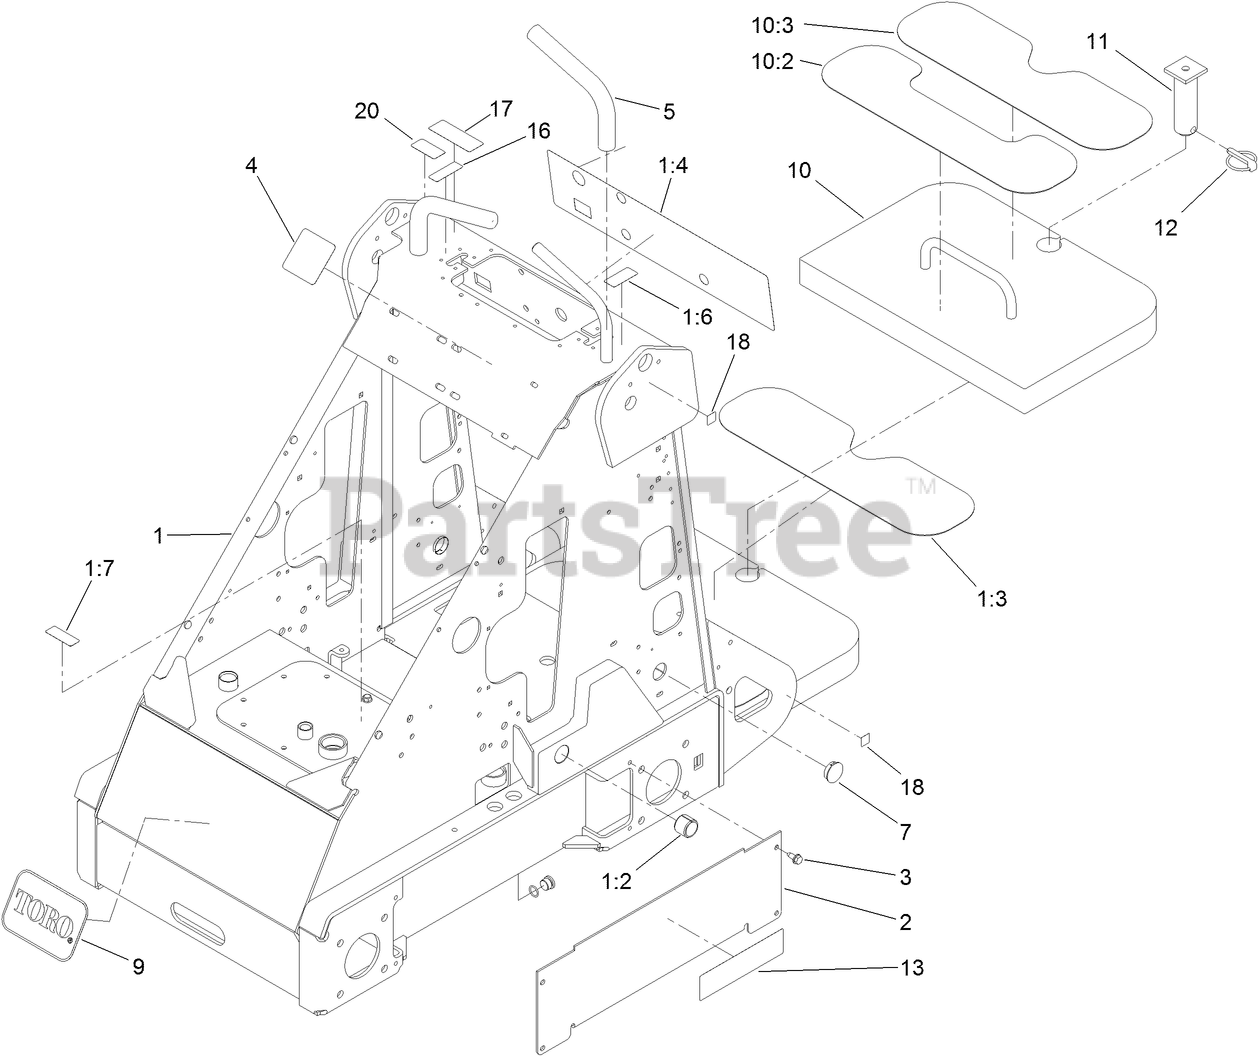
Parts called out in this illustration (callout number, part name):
1	FRAME ASM
1:2	BUSHING-TENSION
1:3	TREAD-FOOT
1:4	DECAL-PANEL, CONTROL
1:6	DECAL-THROTTLE
1:7	DECAL-OIL, HYD
2	COVER-HOSE
3	SCREW-HWHTF
4	DECAL-SELECTOR, SPEED
5	GRIP-CUSHION
7	PLUG-HOLE
9	DECAL
10	COUNTERWEIGHT ASM
10:2	TREAD-FOOT
12	PIN-LYNCH
16	DECAL-CHOKE
17	DECAL-ARRESTER, SPARK
18	DECAL-POINT, LIFT
20	DECAL-PROTECTION, EAR
